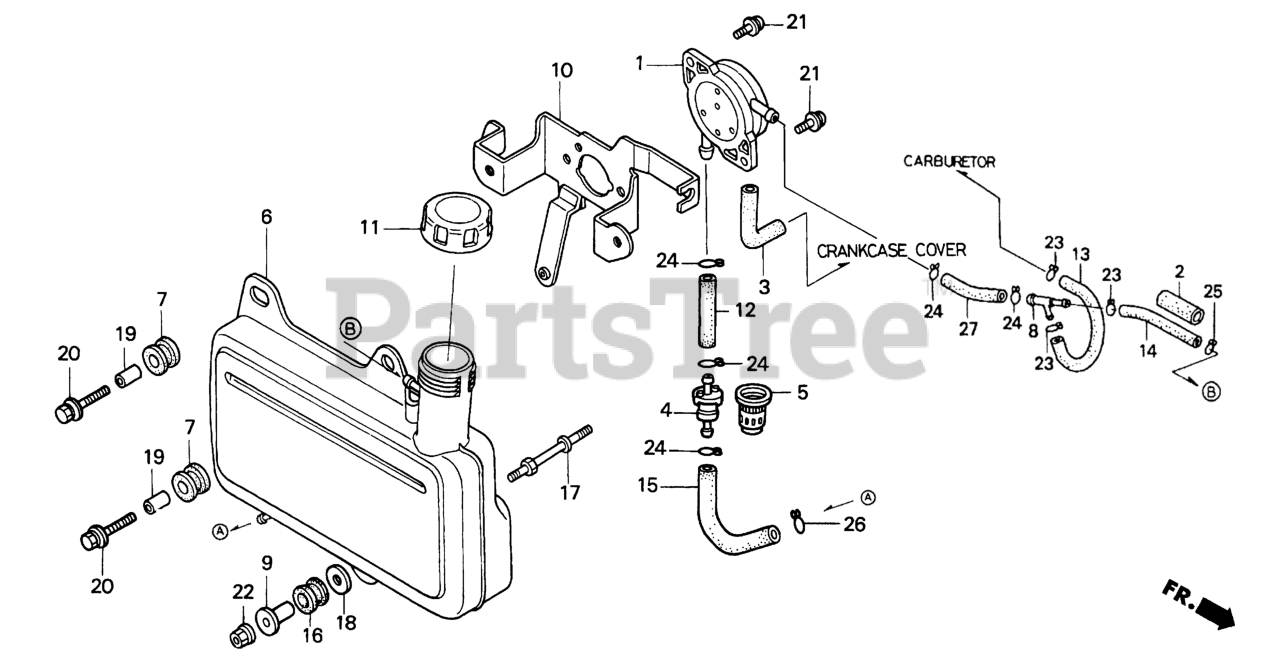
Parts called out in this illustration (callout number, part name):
1	PUMP ASSY., FUEL
1	PUMP ASSY., FUEL (MSDS)
2	RUBBER, SUPPORTER (107MM)
3	TUBE, DIAPHRAGM
4	FILTER, FUEL
5	SUSPENSION, STRAINER
6	TANK, FUEL
7	RUBBER B, TANK MOUNTING
8	JOINT, FUEL TUBE
9	COLLAR, FUEL TANK SETTING
10	STAY A, FUEL TANK
11	CAP ASSY., FUEL TANK
12	TUBE, FUEL TANK
13	TUBE, FUEL
14	TUBE, FUEL RETURN
15	TUBE, FUEL PUMP
16	CUSHION, RR. FENDER
17	BOLT, FUEL TANK STUD (H=30MM)
18	WASHER (6MM)
19	COLLAR (14X6.1)
20	BOLT-WASHER (6X25)
21	SCREW-WASHER (5X14)
22	NUT, FLANGE (6MM)
23	CLIP, TUBE (B8)
24	CLIP, TUBE (B10)
25	CLIP, TUBE (C9)
26	CLIP, TUBE (C11)
27	BULK HOSE, FUEL (5.5X3000) (Honda Code 5338587). (5.5X150)
